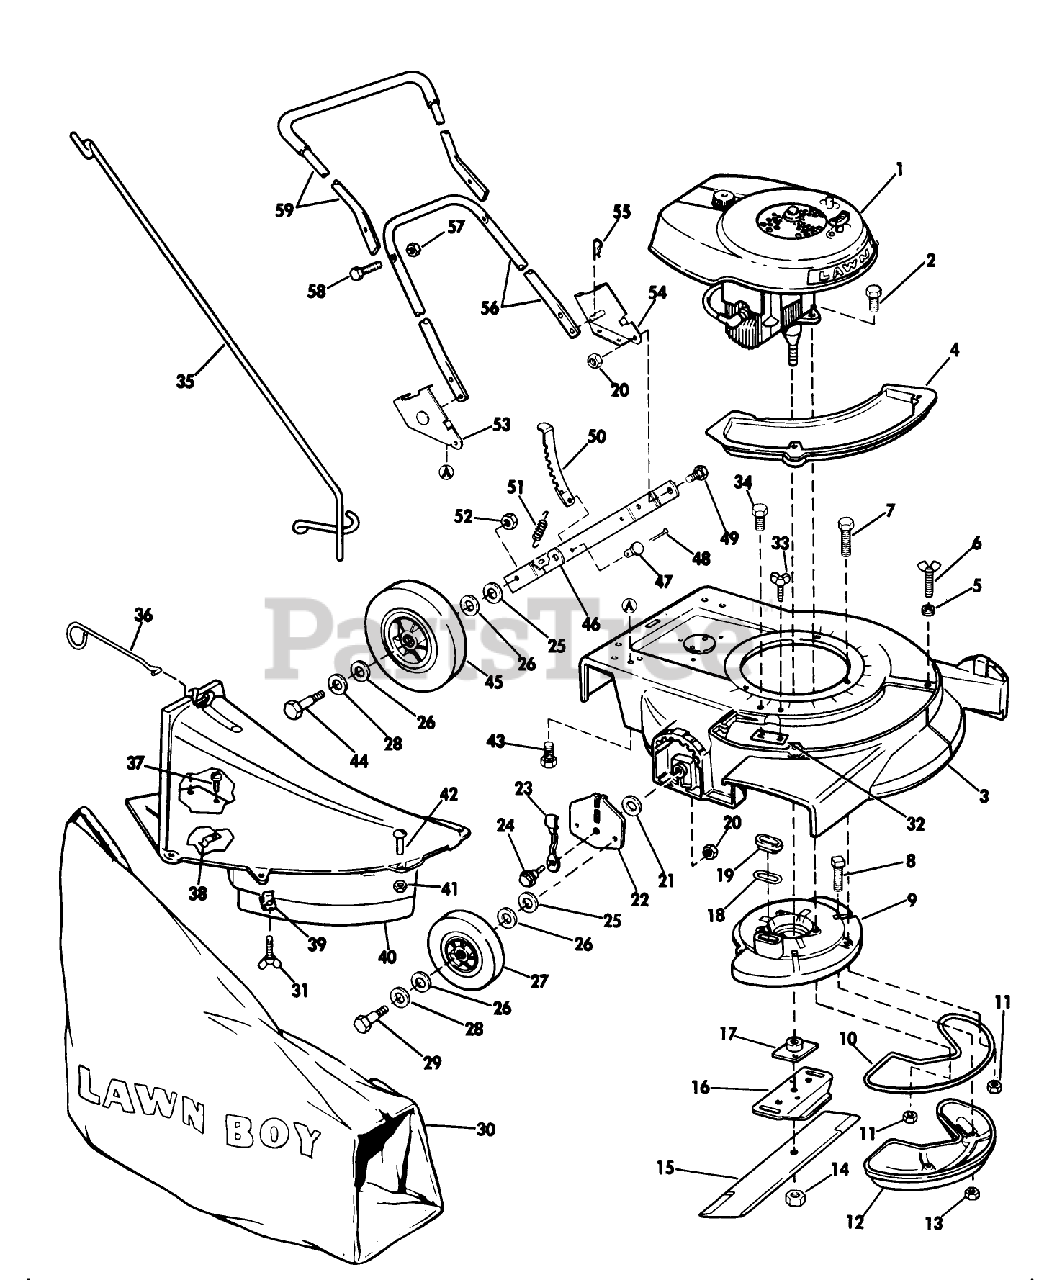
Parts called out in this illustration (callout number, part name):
13	LOCKNUT E
14	NUT-BLADE
17	PLATE AND COLLAR ASM
18	GASKET S
25	WASHER WROUGHT
29	BOLT WHEEL
30	89802 LB WHOLE GOODS
39	SPEED NUT ARDEN
40	Chute Skirt Assembly (Includes Hardware)
49	BOLT-SHOULDER
51	SPRING N.A.S
52	LOCKNUT
55	HAIR PIN
